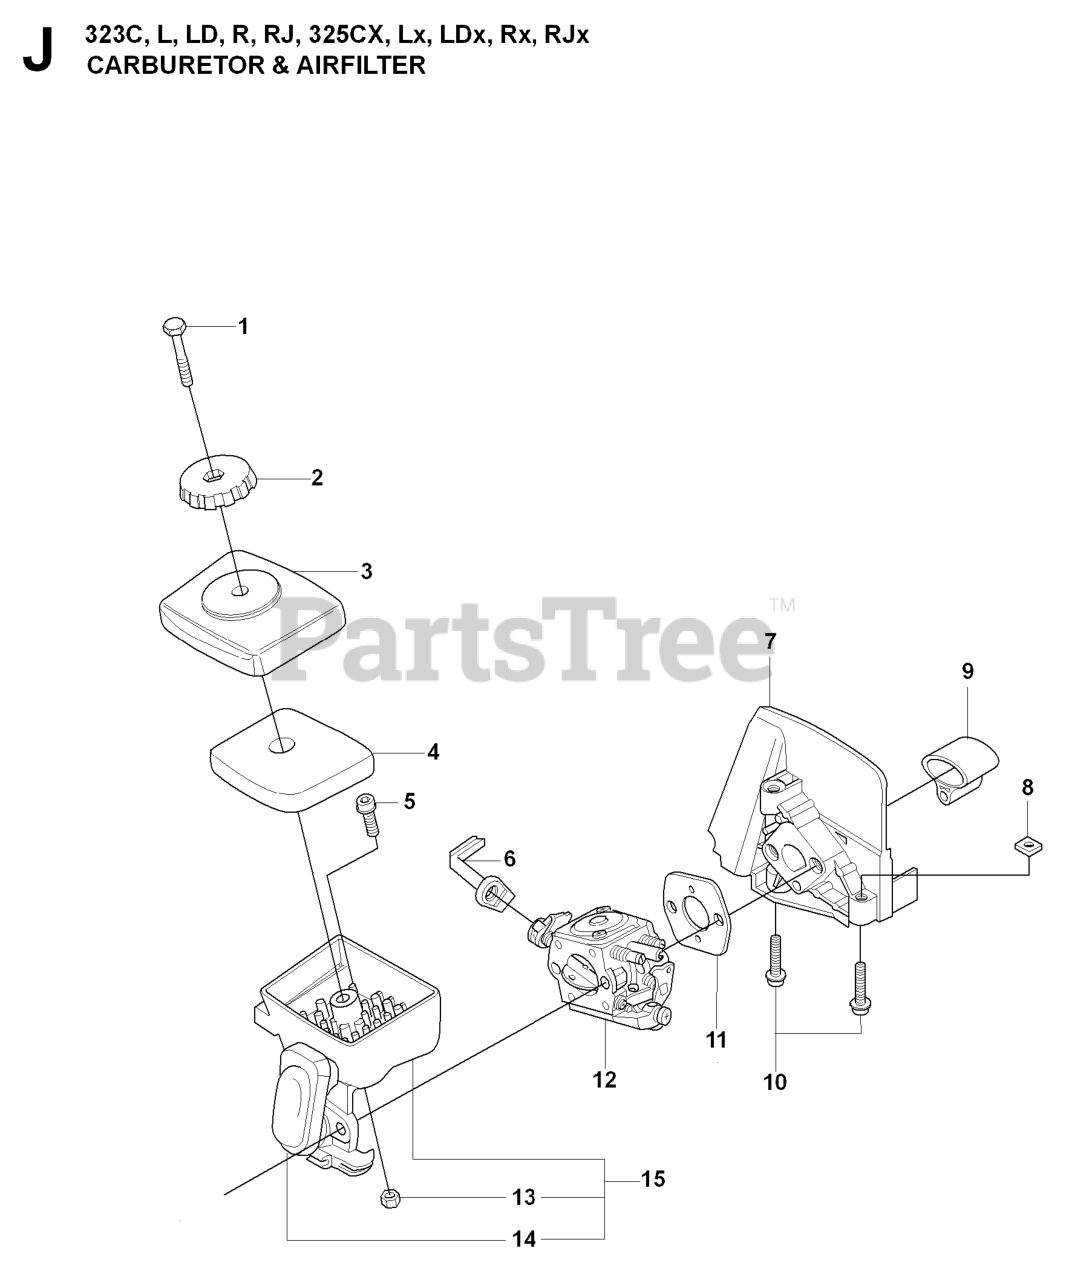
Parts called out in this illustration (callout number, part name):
3	AIR FILTER COVER
4	AIR FILTER (READY-OILED)
6	CHOKE CONTROL
12	CARBURETOR
14	CAP FILTER HOLDER
15	FILTER HOLDER
